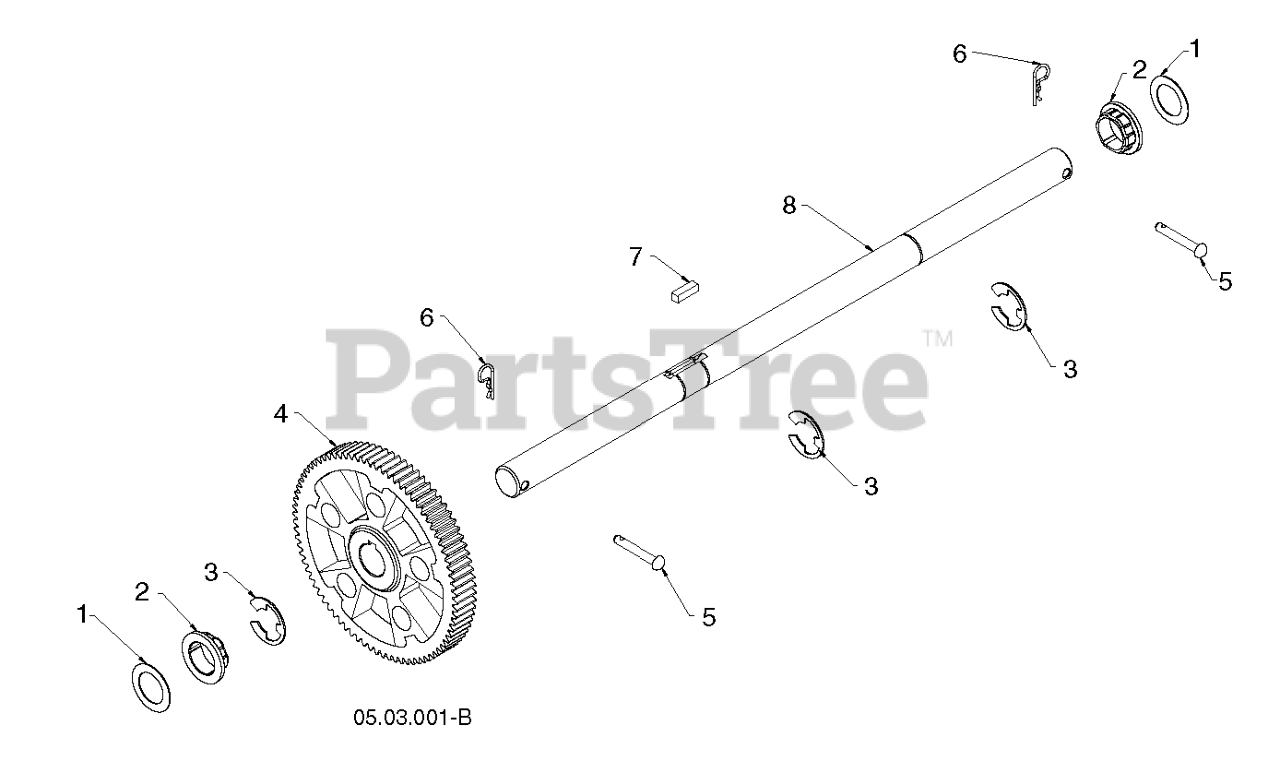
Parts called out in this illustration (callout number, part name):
1	WASHER 1.00
2	BUSHING.HEX.1.SHAFT
3	E RING HYT
4	GEAR.80T.DRIVEN.2PC
5	RIVET
6	RETAINER M
7	KEY, SQUARE 1/4 X .875
8	SHAFT SHAFT,AXLE,
